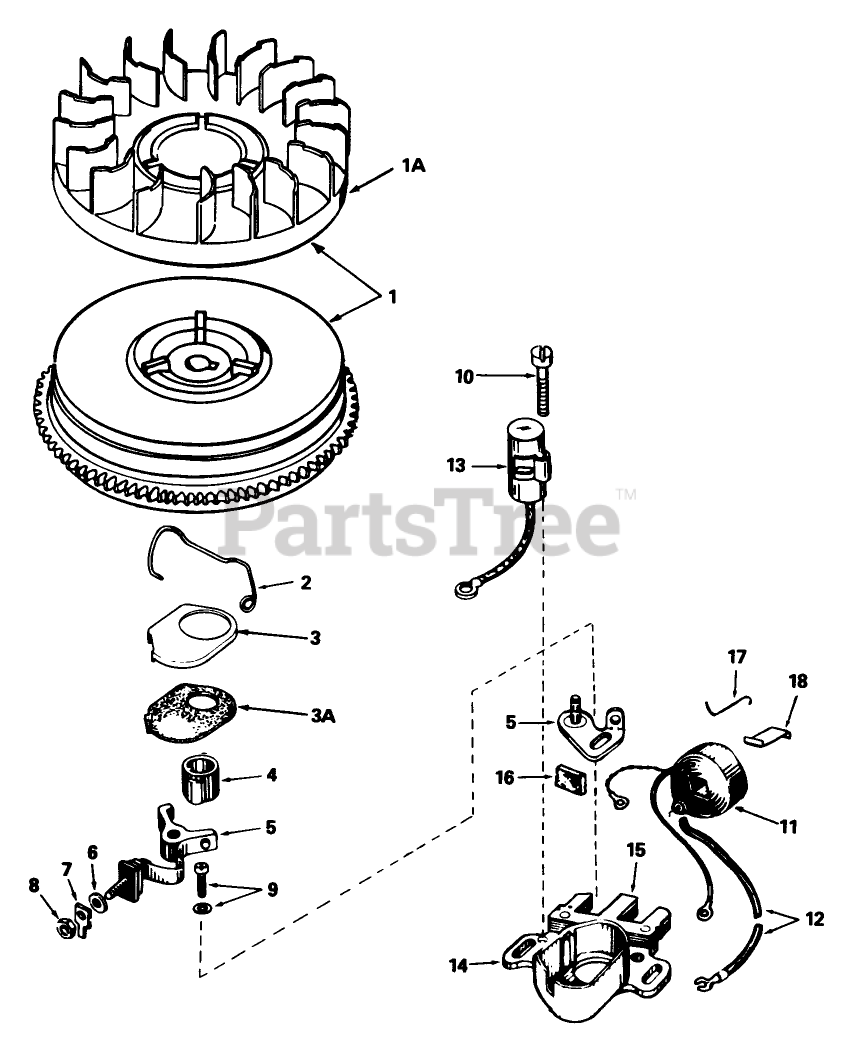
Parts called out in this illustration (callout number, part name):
1	Flywheel (Incl. Nos. 1A, 3 3A)
1A	Fan
2	Spring Breaker Box
3	Cover-Dust
3A	Gasket, Dust Cover
4	Cam-Breaker
5	Breaker Assy.
6	Washer
7	Terminal, Ground
8	DECAL
9	Breaker Screw
10	Condenser Screw
11	Coil Assy. (Incl. No. 12)
12	Wire, Lead
13	Condenser
14	Core Plate
15	Stator Assy. (Incl. Ref. #2 thru 11, 13, 14, 16, 17 19)
16	Felt,Cam Wiper
17	Clip, Coil
18	Spring Coil Wedge
